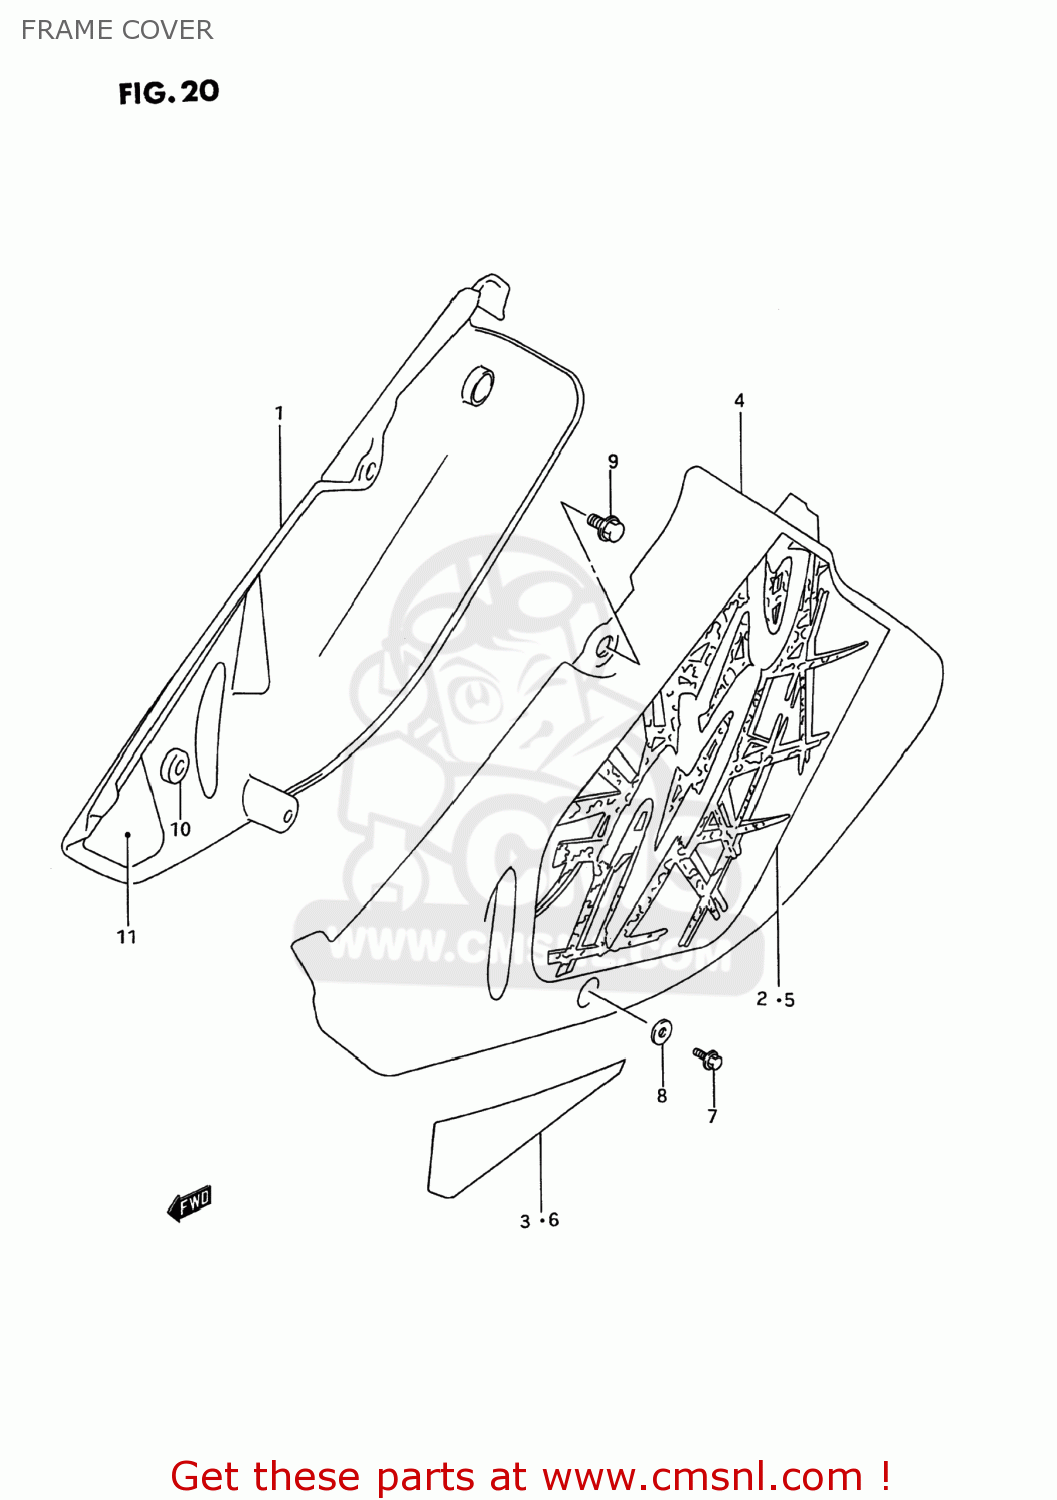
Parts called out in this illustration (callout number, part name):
1	COVER,FRAME,RIGHT
2	EMBLEM,FRAME COVER,RIGHT
3	EMBLEM,FRAME COVER,RIGHT
4	COVER,FRAME,LEFT
5	EMBLEM,FRAME COVER,LEFT
6	EMBLEM,FRAME COVER,LEFT
7	BOLT
8	WASHER
9	BOLT
10	CUSHION
11	SHIELD,FRAME COVER,RIGHT H
